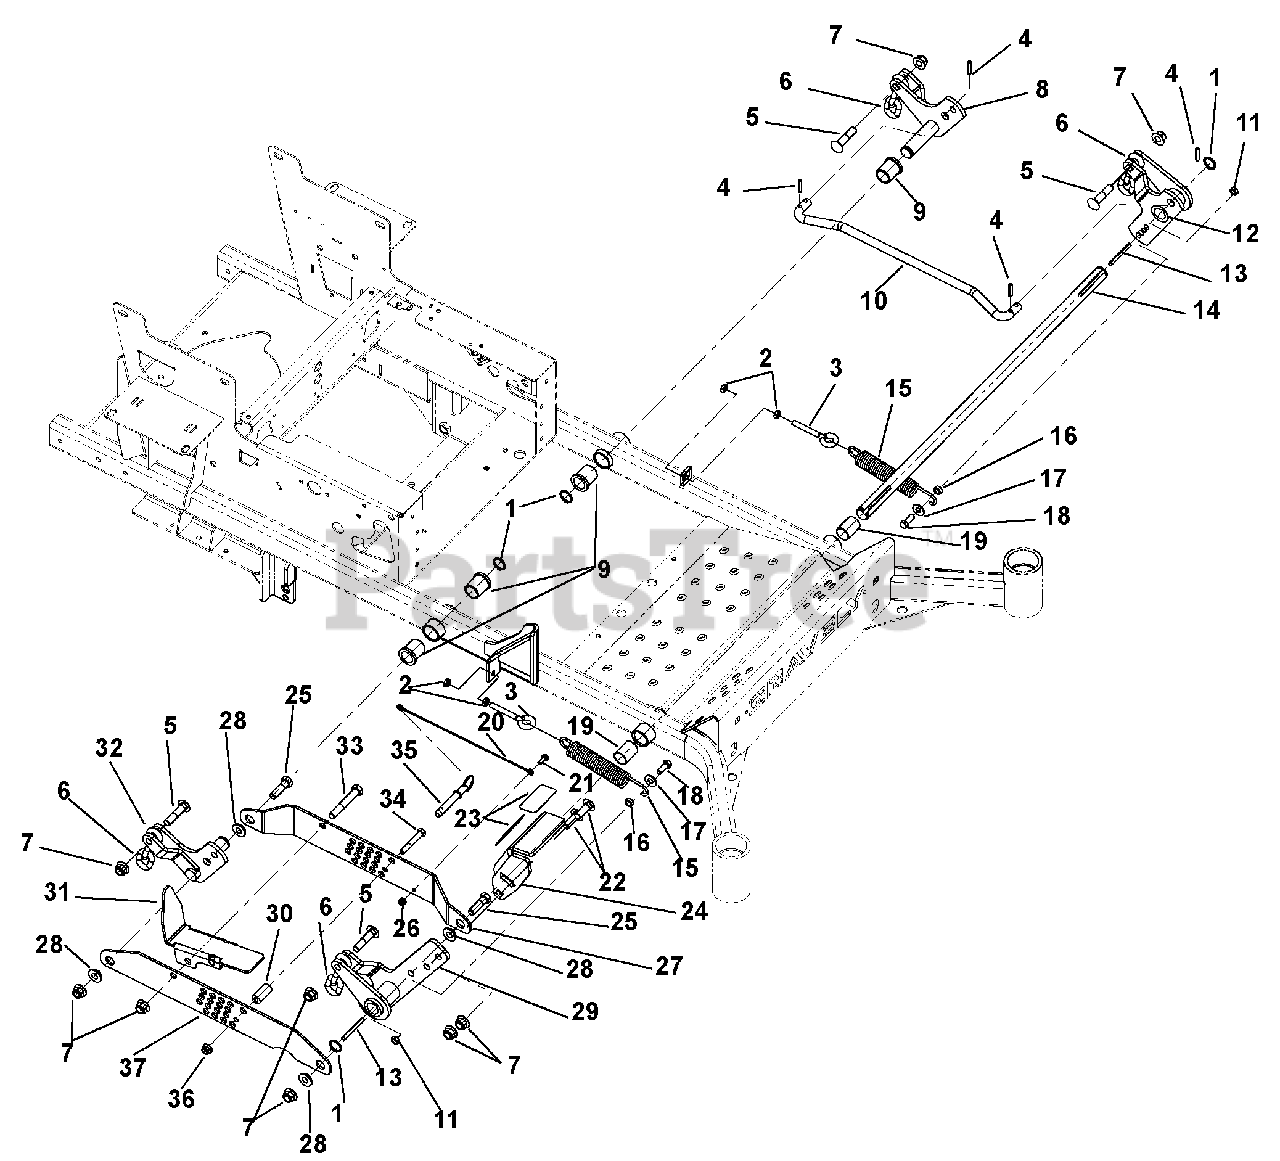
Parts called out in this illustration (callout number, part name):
1	Ring, Retaining, External 1.00 x .078
2	Nut, Hex, Jam .375-16
3	Bolt, Eye .375-16 x 2.50
4	Pin, Roll .25 x 1.25 Stainless Steel
5	Bolt, Round Head Square Neck .50-13 x 2.25
6	Chain, 3-Link .38 Deck Lift
7	Nut, Locking Nylon Flange .50-13
8	Weldment, LH Rear Deck Lift
9	Bushing, Flange 1.00 x 1.25 x 1.50 x 1.50
10	Rod, Lift Assist 19.35"
11	Nut, Locking Center Jam .375-16
12	Weldment, Front LH Deck Lift
13	Key, Square .25 x 2.50 x .25 SAE
14	Shaft, PT100 Front Mower Lift
15	Spring, Tension .162 x 1.25 x 8.25 Weldment 25
16	Bushing, Sleeve .377 x .624 x .235
17	Washer, Flat Steel .438 x 1.00 x .083
18	Bolt, Hex .38-16 x 1.00
19	Bushing, 1.00 ID x 1.125 OD x 1.50
20	Cable, 12.0 Lanyard, Nylon
21	Bolt, Hex .25-20 x .75
22	Bolt, Round Head Square Neck .50-13 x 1.50
23	Grip, Pedal 1.50 x 3.00
24	Adjustable Foot Lift Pedal, Black
25	Bolt, Hex .50-13 x 1.75
26	Nut, Locking Nylon Flange .25-20
27	RH Lift/Cut Height Bracket, Inboard
28	Bushing, Flange .515 x .750 x .395 x 1.120
29	Weldment, Adjustable Deck Foot Lift
30	Spacer, .375 x .750 x 1.54
31	Mechanical Lock-up Weldment, Black
32	Weldment, RH Rear Deck Lift
33	Bolt, Hex .50-13 x 3.25
34	Bolt, Hex .38-16 x 2.50
35	Pin, .50 x 2.00 Usable Length Ball
36	Nut, Locking Nylon Flange .38-16
37	RH, Lift/Cut Height Bracket, Outboard
